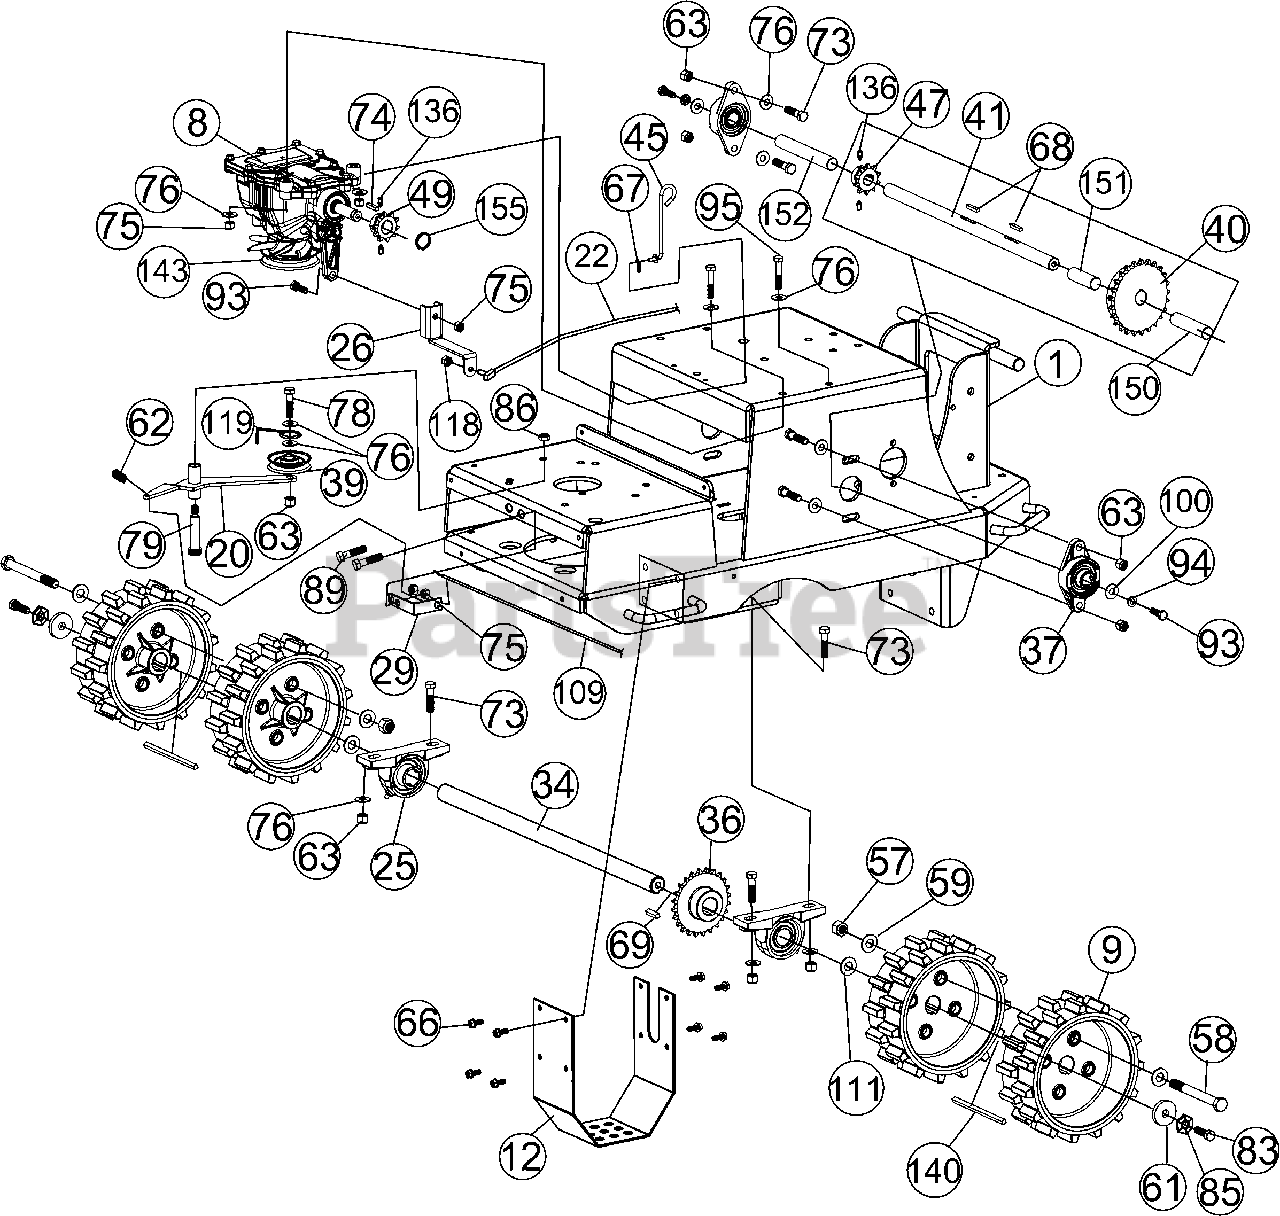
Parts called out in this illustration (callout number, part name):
1	FRAME WA SC
8	TRANSMISSION RT310
9	WHEEL DRIVE SOD CUTTER
12	GUARD AXLE
20	IDLER ARM WA
22	SPEED CONTROL SC
25	PILLOW BLOCK 1"
26	SHIFT ARM EXTENSION
29	TAB MOUNT WHEEL CLUTCH CABLE
34	AXLE LONG SC
36	SPROCKET 40C25 1" BORE
37	BEARING 3/4" CAST FLANGE W/ZERK
39	IDLER PULLEY
40	SPROCKET 40B25 1" BORE
41	JACKSHAFT 1.00 X 17.06 LG 4140HT PLATED
45	ROD TRANSMISSION BYPASS
47	SPROCKET 40B10 1" BORE
49	SPROCKET 40B10 5/8" BORE
57	NUT LOCK 1/2"-13 HEX
58	SCREWCAP 1/2"-13 X 4 3/4" HCS ZP
59	WASHER 1/2" SAE
61	WASHER 1.5 OD X .453 ID X .25
62	SPRING EXTENSION
63	NUT LOCK 3/8"-16
66	SCREW SELF TAP 1/4"-20 X 3/4" TYPE 23
67	PIN 1/4" RUE RING
69	KEY 1/4" SQ X 1"
73	SCREWCAP 3/8"-16 X 1 1/2" HC ZP
74	KEY 3/16" SQ X 1"
75	NUT LOCK 5/16"-18
76	WASHER 5/16" FLAT
78	SCREWCAP 3/8"-16 X 2" HCS ZP
79	SHOULDER BOLT 1/2" X 2"
83	SCREWCAP 3/8" - 16 X 1 1/4" GR 5 ZP W/RED PATCH
84	SNAP RING TRUARC 5/8"
85	WASHER LOCK 3/8" TWISTED TOOTH
86	NUT LOCK 3/8"-16 LT WT TH ZP
89	SCREWCAP 1/4"-20 X 3/4" HCS ZP
93	SCREWCAP 5/16"-18 X 1" GR 5 HCS ZP
94	LOCK WASHER 5/16" S/T MED
95	SCREWCAP 5/16"-18 X 2" GR 5 HCS ZP
98	WASHER 1/4" FLAT
100	WASHER 3/8"FC
109	CABLE CONTROL DRIVE QV
111	WASHER 1" SAE
118	NUT 1/4" - 28 HEX ZP
119	BELT FINGER DRIVE IDLER PULLEY
136	SCREWSET 1/4"-20 X .375 CUP PT W/NYLOK
140	KEY 1/4" X 4.00"
143	PULLEY AND FAN KIT RT310
150	SPACER 1.25 X .109 WALL 3.35 LG
151	SPACER 1.25 X .109 WALL X 2.787 LG
152	SPACER 1.25 X .109 WALL X 6.578 LG
155	RETAINING RING 5/8"
